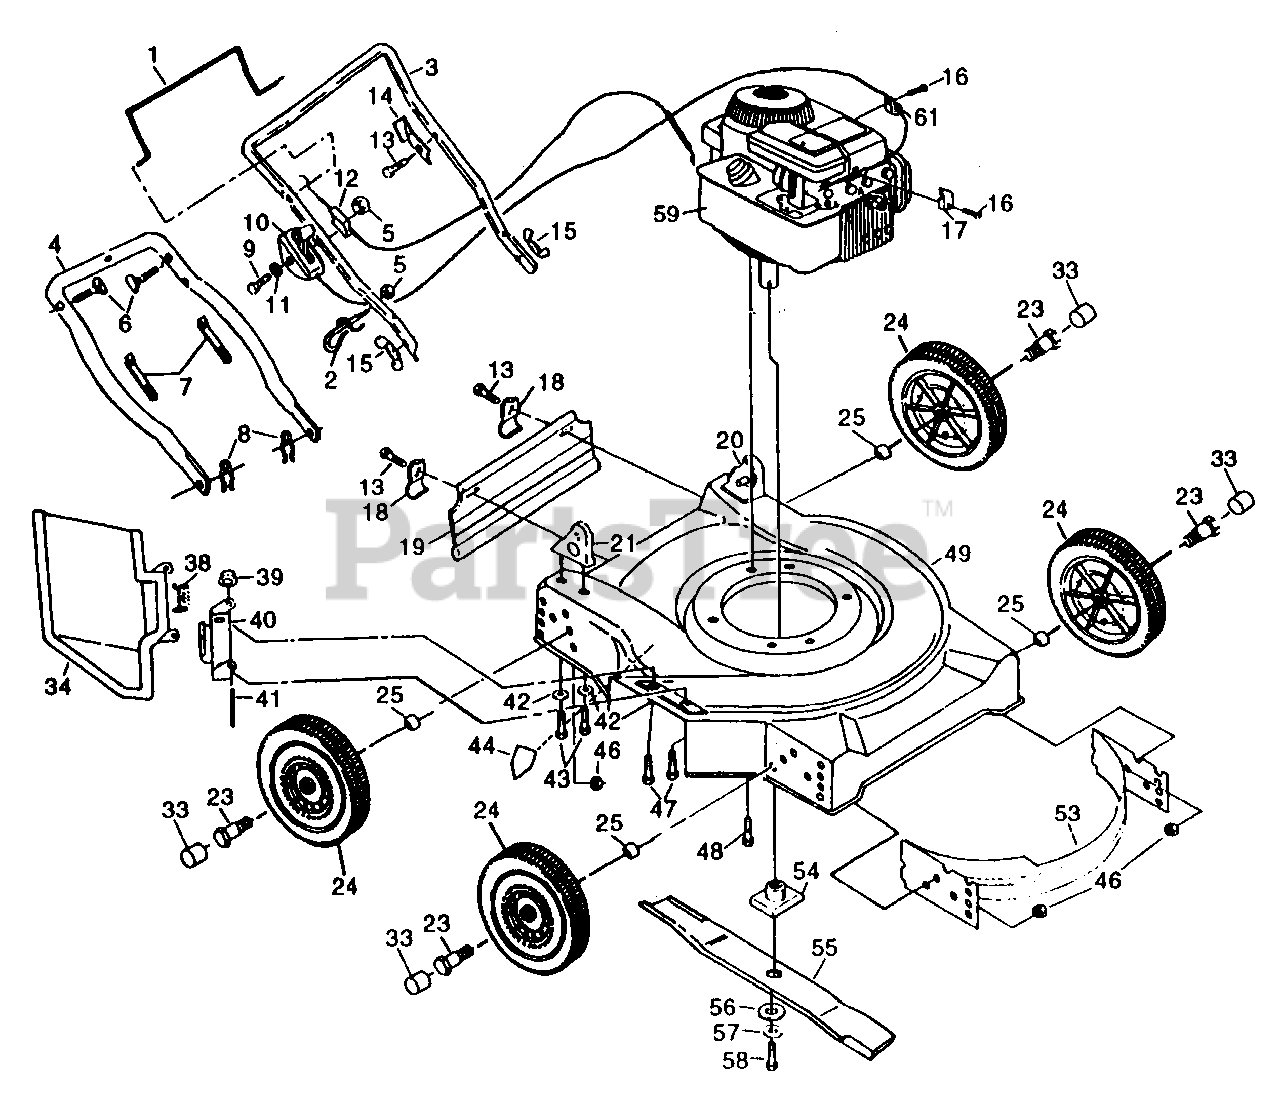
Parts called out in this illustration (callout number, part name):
1	Control Bar (AYP part number)
2	Rope Guide
3	Upper Handle (AYP part number)
4	Lower Handle (AYP part number)
5	Locknut (AYP part number)
6	Handle Bolt 5/16-18 x 1-3/4 (AYP part number)
7	Wire Tie (AYP part number)
8	Hairpin Cotter (AYP part number)
9	Machine Screw 1/4-20 x 2.12 (AYP part number)
10	Throttle Control
11	Washer (AYP part number)
12	Engine Zone Control Cable
13	Hex Washer Head Screw #10-24 x 1/2 (AYP part number)
14	Up-Stop Bracket (AYP part number)
15	Wing Nut (AYP part number)
16	Screw #10 x 5/8 (AYP part number)
17	Cable Clamp (AYP part number)
18	Skirt Bracket (AYP part number)
19	Rear Deflector
20	Handle Bracket Assembly (Left) (AYP part number)
21	Handle Bracket Assembly (Right) (AYP part number)
23	Shoulder Bolt 3/8-16 x 2-1/2 (AYP part number)
24	Wheel Assembly (AYP part number)
25	Wheel Spacer
33	Hubcap (AYP part number)
34	Discharge Guard
38	Torsion Spring (AYP part number)
39	Push On Speed Nut (AYP part number)
40	Deflector Hinge (AYP part number)
41	Hinge Rod (AYP part number)
42	Flat Washer (AYP part number)
43	Screw 5/16-18 x 3/4 (AYP part number)
44	Danger Decal (AYP part number)
46	Locknut 3/8-16 (AYP part number)
47	Hex Head Thd. Rolling Screw 1/4-20 x 3/4 w/ Sems (AYP part number)
48	Hex Head Thread Rolling Screw 3/8-16 x 1 (AYP part number)
49	Mower Housing (Incl. Ref. #44)
53	Front Baffle (AYP part number)
54	Blade Adapter (AYP part number)
55	Blade 20"
56	Hardened Washer (AYP part number)
57	Helical Lockwasher 3/8 (AYP part number)
58	Hex Head Screw 3/8-24 x 1-3/8 (Grd. 8)
61	Guide Clip (AYP part number)
